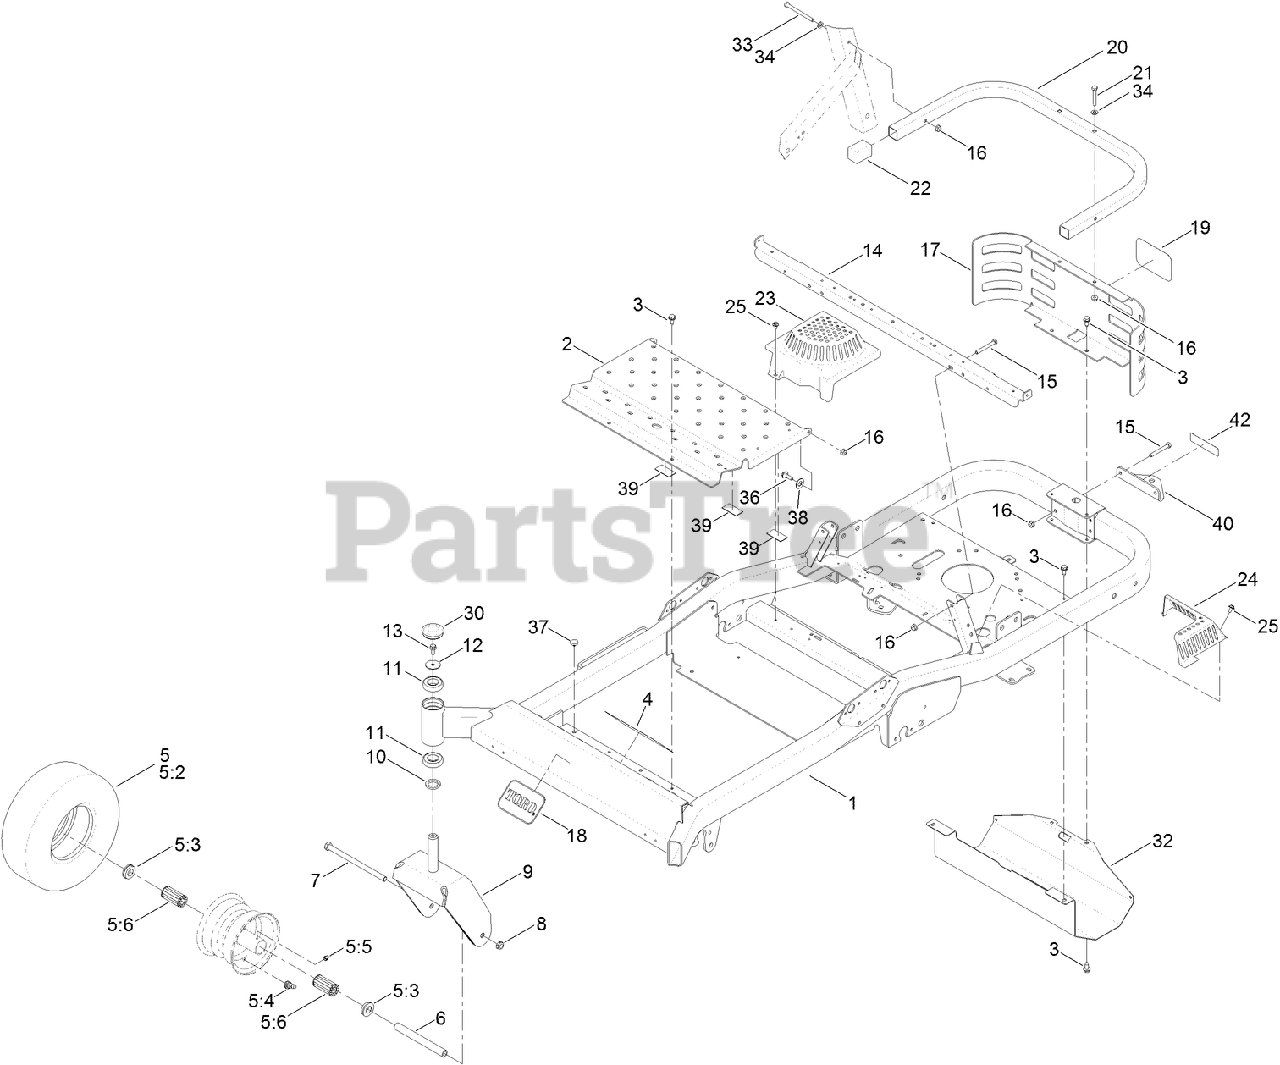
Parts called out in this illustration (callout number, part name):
1	FRAME ASM
2	PAN-FLOOR
3	SCREW-HWHTF
4	DECAL-DANGER
5	TIRE AND WHEEL ASM
5:3	BUSHING-FLANGE
5:4	VALVE
5:5	FITTING-ZERK
5:6	BEARING
6	SPANNER-WHEEL, CASTER
7	SCREW-HH
8	NUT-HEX
9	CASTER FORK ASM
10	WASHER-THRUST
11	BEARING-BALL
12	WASHER-FLAT
13	SCREW-HHF
14	SUPPORT-SEAT
15	SCREW-HH
16	NUT-HF, NI
17	GUARD-REAR
18	DECAL
20	TUBE-GUARD
21	SCREW-HH
23	COVER-FAN, RH
24	COVER-FAN, LH
25	SCREW-HHFTF
30	CAP-GREASE
32	SHIELD-HEAT
33	SCREW-HH
34	WASHER-PLAIN
36	SCREW-SHOULDER
37	BUMPER
38	WASHER-TEFLON
39	PAD-RUBBER
40	BRACKET-HITCH
